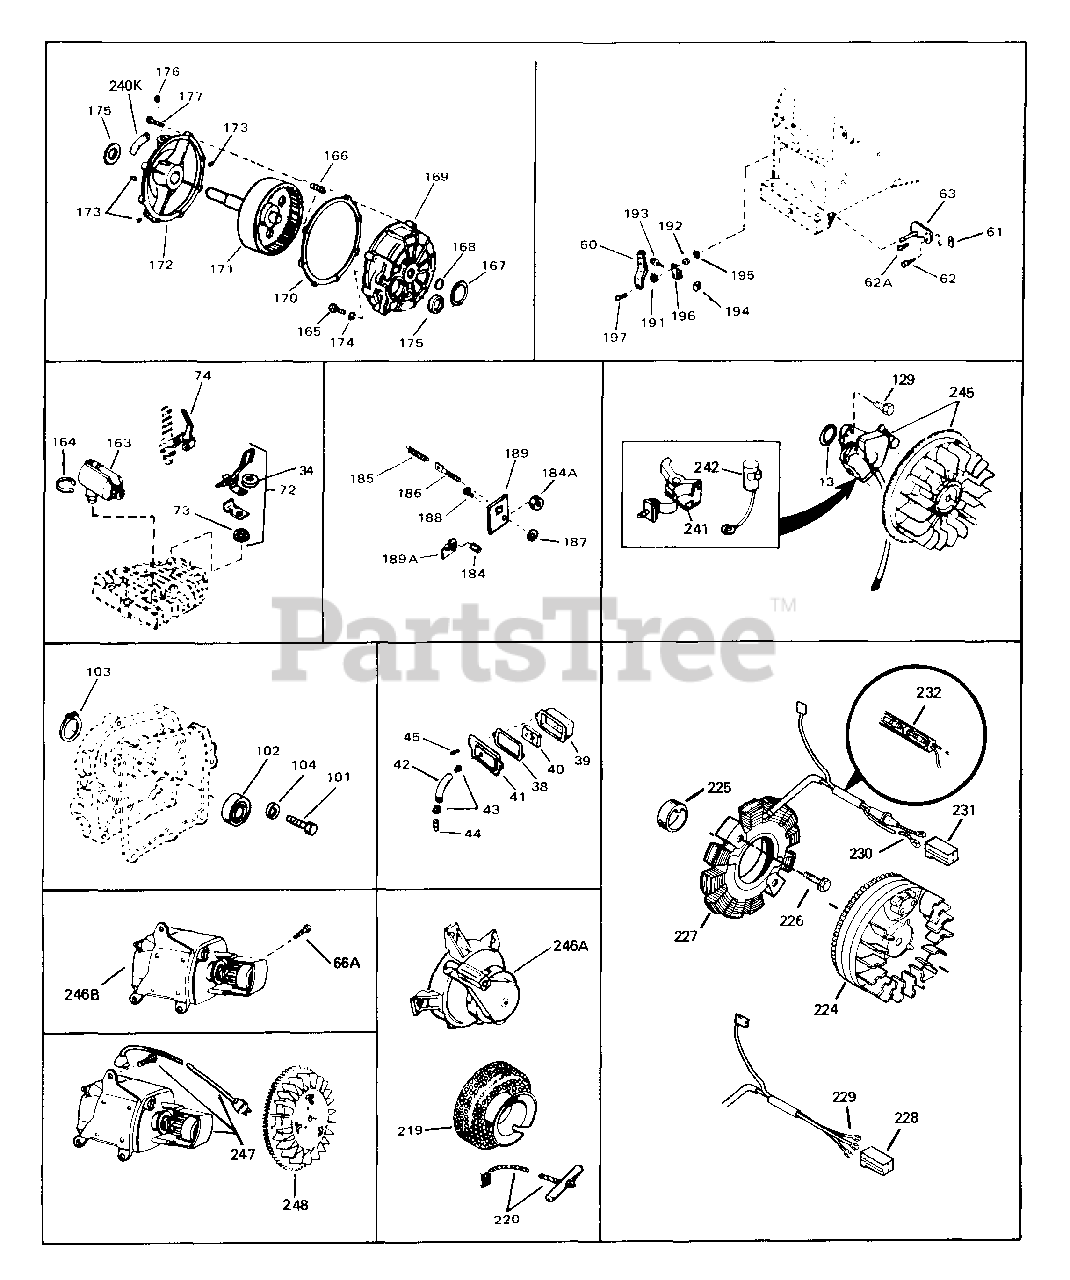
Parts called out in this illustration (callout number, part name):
13	Gasket, Stator
34	Washer, Flat
38	Gasket, Breather
40	Element, Breather
45	Screw, fil. hd. Sems, 10-24 x 1/2
60	Lever, Governor
61	Yoke, Governor
62	Screw, Fil. hd. Sems, 6-40 x 5/16
62A	Screw, Phil. rd. hd. thr'd cutting, 5 -40 x
63	Rod, Governor
129	Screw, Hex hd Sems, 1/4-20 x 5/8
184	Nut, Speed adj.
185	Spring Extension
186	Bolt, Governor spring adj.
187	Washer, Lock
188	Screw, Hex washer hd. self-tap, Sems, 10-24
189A	Bracket, Speed control
191	Washer, Lock, #8
192	Nut & Lockwasher, Hex Keps, 8-32
193	Screw, Hex washer hd., 10-32 x 3/4
194	Nut, Square, 10-32
195	Ring, Retaining
196	Clamp, Governor lever
197	Screw, Hex washer hd., 8-32 x 5/16
241	Contact Assy., Breaker
242	Condenser
245	Magneto, Tecumseh
247	Starter Motor Kit (110-120 Volt)
248	Flywheel
